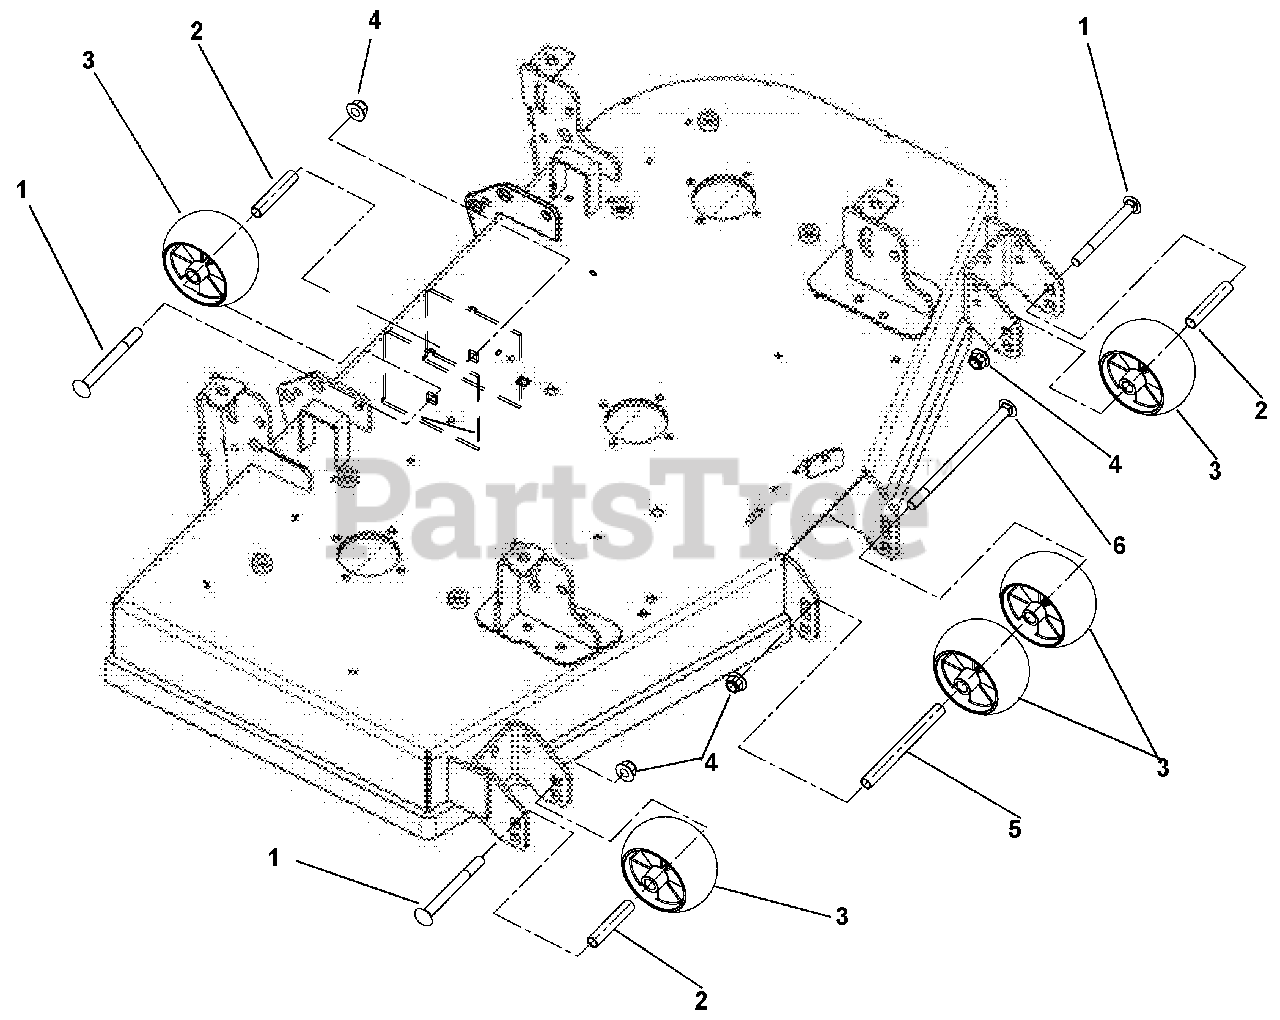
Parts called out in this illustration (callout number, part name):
1	Bolt, Round Head Square Neck .50-13 x 5.00 (991300)
2	Spacer, .510 x .625 x 3.35 (991300)
3	Anti-Scalp Wheel (991300)
4	Nut, .50-13 Nyloc Flange (991300)
6	Bolt, Round Head Square Neck .50-13 x 8.50
